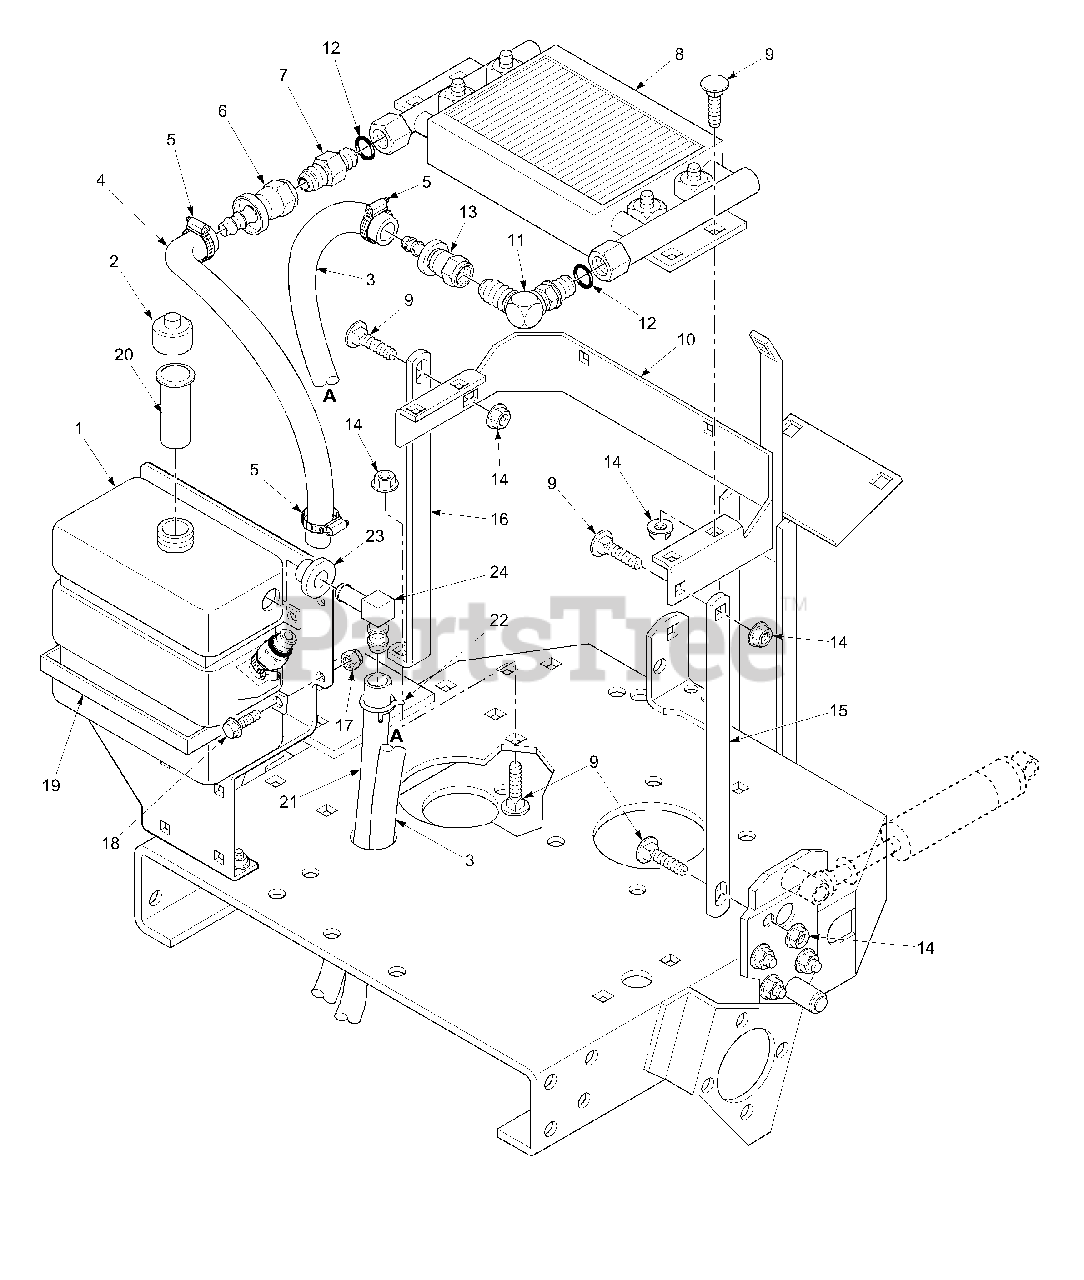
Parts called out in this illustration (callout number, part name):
1	Tank, Hydraulic
2	Cap, Hydraulic Tank
3	Hose, Pump to Oil Cooler
4	Hose, Oil Cooler to Tank
5	Clamp, Hose
6	Coupling, Flare Swivel
7	Tube, Union
8	Oil Cooler Assembly
9	Carriage Bolt, 5/16-18 x 3/4"
10	Bracket, Oil Cooler
11	Elbow, 90 Degrees
12	O-Ring
13	Coupling Flare Swivel
14	Serr. Fl. Hex Head Nut, 5/16-18
15	Brace, L.H. Cooler Support
16	Brace, R.H. Cooler Support
17	Elastic Stop Nut, 1/4-20
18	Serr. Fl. Hex Head CPSCR, 1/4-20 x 3/4"
19	Strap, Oil Tank
20	Filler Neck Insert
21	Hose, 1/4" Pushlock, Order by the inch
23	Bushing
24	90 Degree Elbow
